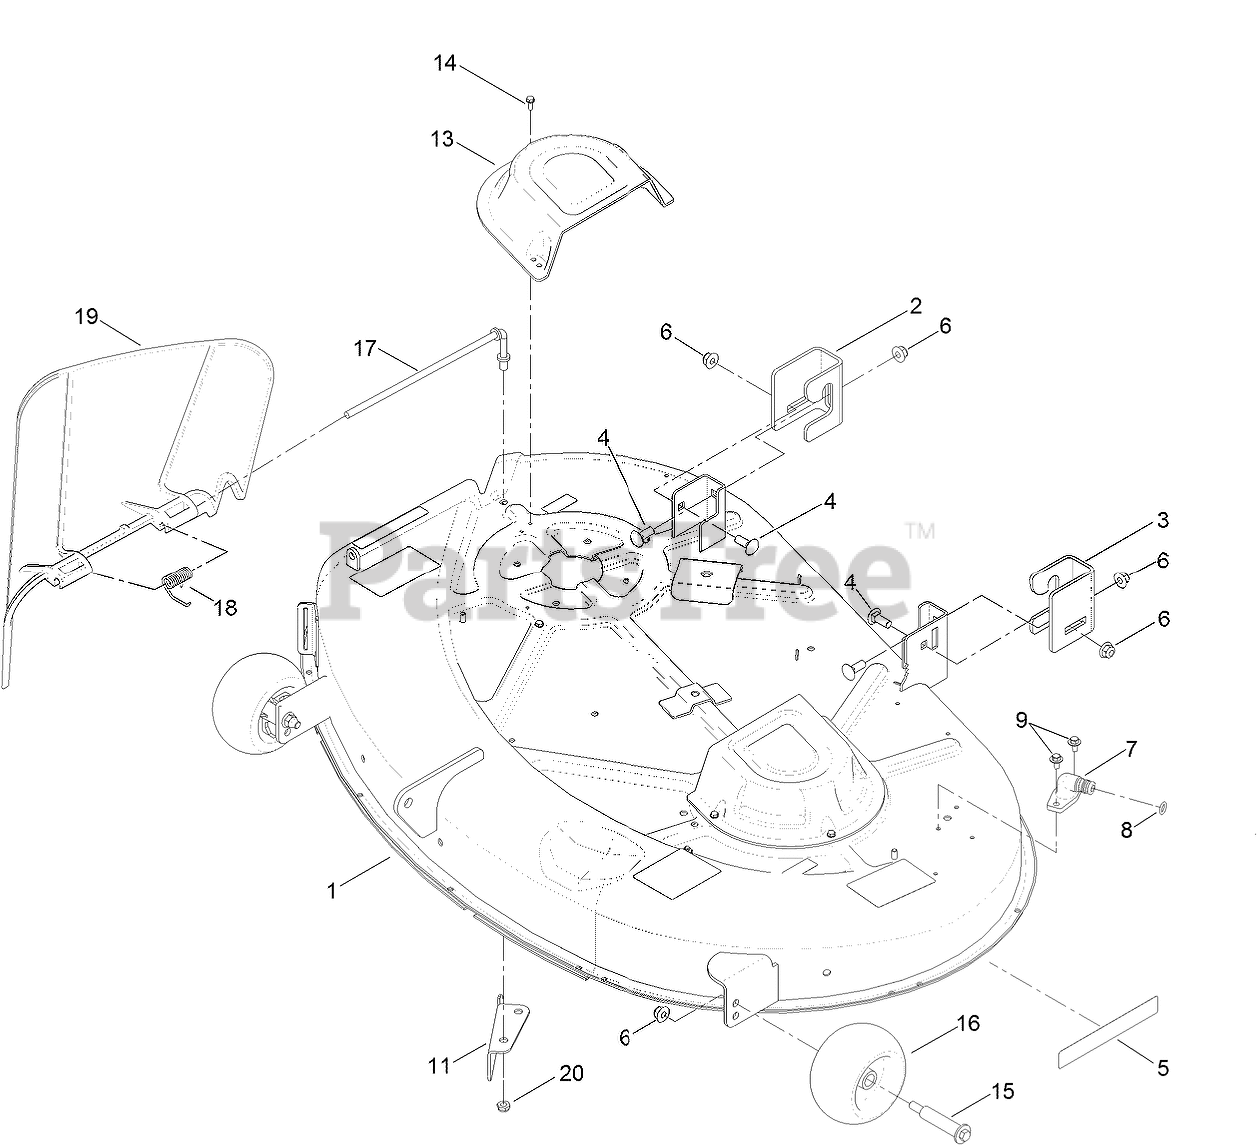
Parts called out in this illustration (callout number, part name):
1	42 INCH DECK AND DECAL ASM
2	BRACKET-HANGER, RH
3	BRACKET-HANGER, LH
4	BOLT-CARR
5	DECAL-RECYCLER
6	NUT-HF, NI
7	FITTING-WASHOUT
8	O-RING
9	SCREW-HHFTF
11	BAFFLE-CUTOFF
13	COVER-BELT
14	SCREW-TAPTITE
15	BOLT-SHOULDER
16	ROLLER-SCALP, ANTI
17	ROD-PIVOT
18	SPRING-TORSION
19	DEFLECTOR
20	NUT-LOCK, NI
